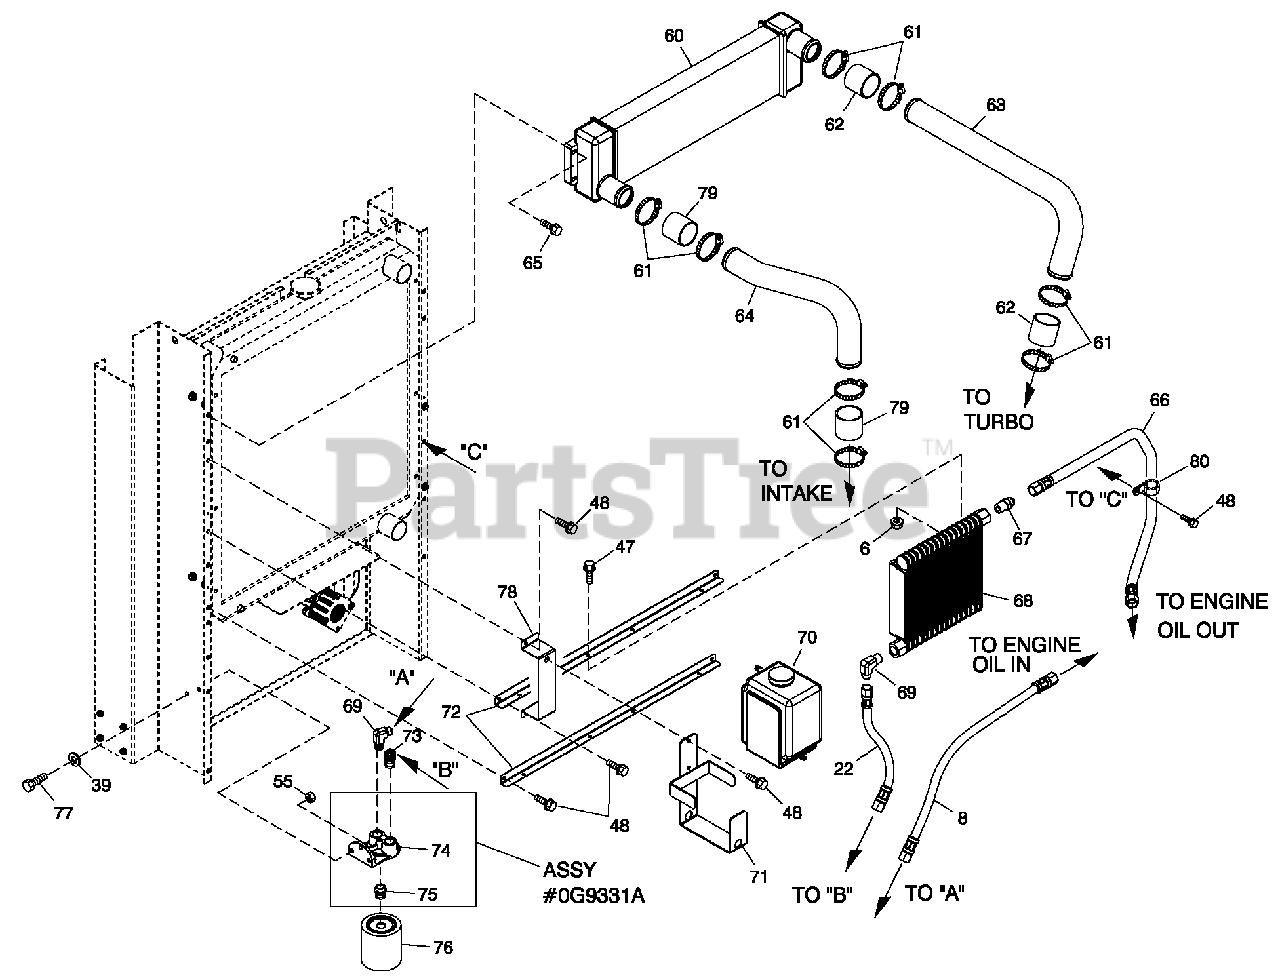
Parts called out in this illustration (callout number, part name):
6	NUT FLANGE M6-1.0NYLOK
8	OIL LINE REMOTE FILTER/ENGINE
22	OIL LINE REMOTE COOLER/FILTER
39	WASHERFLAT 5/16-M8ZINC
47	SCREW HHFCM6-10 X 2 0 G8.8
48	SCREW THF M6-1 X 16 N WAZ/JS
55	NUT HEX LOCK M8-1.25 NY INS
56	BRACKET TENSIONERSPRING
57	CLAMP HOSE #24 B1.06-2.00
58	NUT HEX LOCK 5/16-24 NY INS
59	HOSE 9/32 ID(36" LG)
60	CAC504WX152H X 5 0D 2 .4 L G2
61	CLAMP CNSTTENSON 1.75-2.625
62	HOSE 2"IDX 3.0"LG
63	TUBECAC N G2 TURBO
64	TUBECAC OUT G2 TURBO
65	SCREW THF M6-1 X 30 N WA DELTA
66	OIL LINE REMOTE ENG/COOLER
67	ADAPTOR 1/2 NPT X 37JIC 3/4-16
68	COOLER OIL 2 4 L G2 TURBO
69	ADAPTE R90D JIC 3 7 1 /2NPT X 3/4
70	TANK COOLANT RECOVERY
71	BRACKET COOLANT TANK
72	MOUNT OIL COOLER 2 .4 LG 2
73	ADAPTE R45D JIC 3 7 1 /2NPT X 3/4
74	MOUNT REMOTE OIL FILTER2.4G2
75	NIPPLE-OL FILTER
76	FILTER1.5L/24LG2 OIL
77	SCREW HHC M8-1.25 X 25 C8.8
78	BRACKET RESERVOIR MOUNTING
79	HOSE 2"IDX 3.0"LG
80	CLAMP STLVNL.75 X .343 Z
